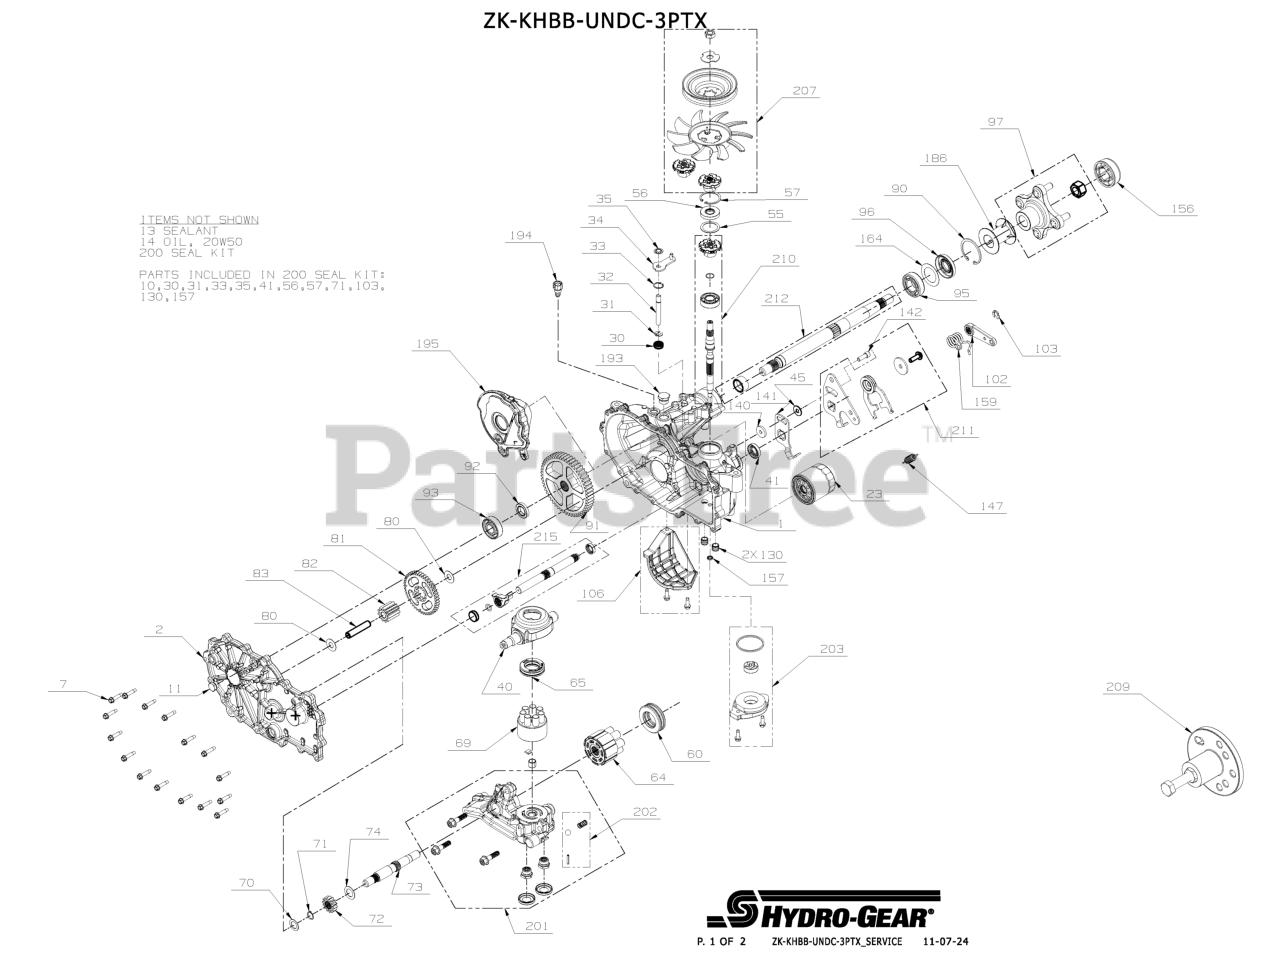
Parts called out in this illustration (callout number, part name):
1	KIT, HOUSING, MAIN, LH, CHRG, CNTL
2	KIT, SIDE COVER, LH
7	SCREW,HEX WASHER 1/4-20X1.125
11	PLUG, EXTERNAL HEX VENT 9/16-18
13	SEALANT TUBE 10.1OZ.
14	FLUID, HYDRO 15W50 QT
14	FLUID, HYDRO 20W50 QT
23	FILTER, HYDRO-GEAR 2800 TRANS
30	SEAL, LIP .375 X .75 X .25
31	RING. RETAINING
33	RING, RET .750
34	HG BYPASS ARM (52370)
35	RING, RTNG .
40	TRUNNION, SWASHPLATE
41	SEAL, LIP 18X32X7
55	WASHER 1.23X1.56X.04
56	SEAL, LIP 17 X 40 X 7 HNBR
57	RING, RET 1.56 INT
60	HG THRUST BEARING (51462)
64	HG 16CC CYLINDER BLOCK (71579)
65	BEARING. THRUST 30 X 52 X 13
69	ASSY, BLOCK 7 PISTON
70	WASHER .63X1.0X.05
71	RING, RET 62 EXT
73	SHAFT, MOTOR
74	WASHER .71 X 1.16 X .04
80	WASHER .5X1.0X.032
83	PIN, JACKSHAFT
90	RING, RETAINING
93	KIT, BEARING
95	BEARING, BALL 25.4 X 52 X 15
96	SEAL, LIP
97	KIT, HUB 4 BOLT
102	HANDLE- ACTUATING
103	CLIP,BRAKE ARM HYDROGEAR 52027
106	KIT, FILTER GUARD
130	TUBE, CHARGE TRIPLE O-RING
141	ARM, NEUTRAL LEFT
142	SHCS 5/16-24X1 PATCH
147	SPRING, EXTENSION
156	SPRING, TORSION, CW
157	KIT, GEROTOR SEAL
159	SPRING, TORSION CCW
164	WASHER, 1.355 x 2.035 x .021 FLAT
186	TUBE, AXLE 2.03
194	KIT, CENTER SECTION, LH
195	KIT, FAN/PULLEY
200	KIT, SEAL
201	KIT-CENTER SETION- LH- CHRG
202	KIT, CHARGE RELIEF
203	KIT, CHARGE
207	KIT- FAN/PULLEY
209	HUB PULLER 5 BLT HYDGEAR 72320
210	KIT, INPUT SHAFT
211	BI-DIRECTIONAL KIT
212	KIT, SHAFT, AXLE
215	KIT, OUTBOARD, RH ROT A / LH ROT B
